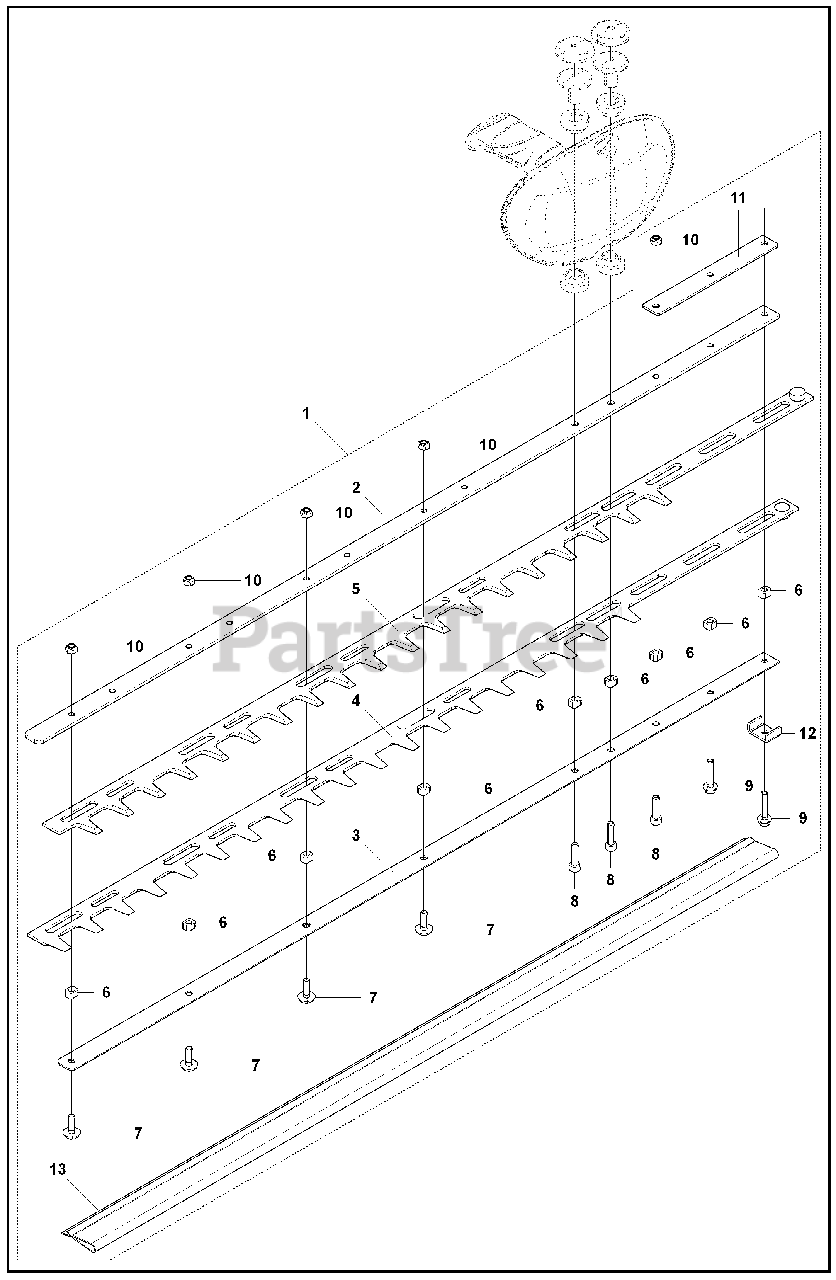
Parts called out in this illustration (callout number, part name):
1	BLADE ASSY
2	PLATE, upper
3	PLATE, lower
4	BLADE, lower
5	BLADE, upper
13	COVER
